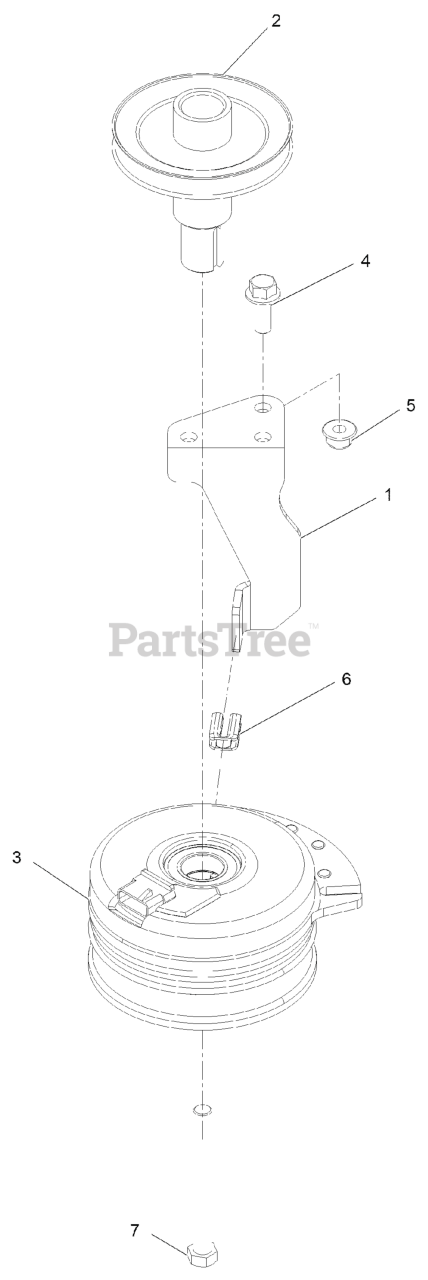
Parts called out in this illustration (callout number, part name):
1	Stop - Clutch (Narrow)
2	Pulley-Engine
3	CLUTCH-ELECTRIC
4	SCREW-HHF 3/8-16 X 1
5	NUT-HF, NI
6	ISOLATOR-CLUTCH
7	SCREW-HH
